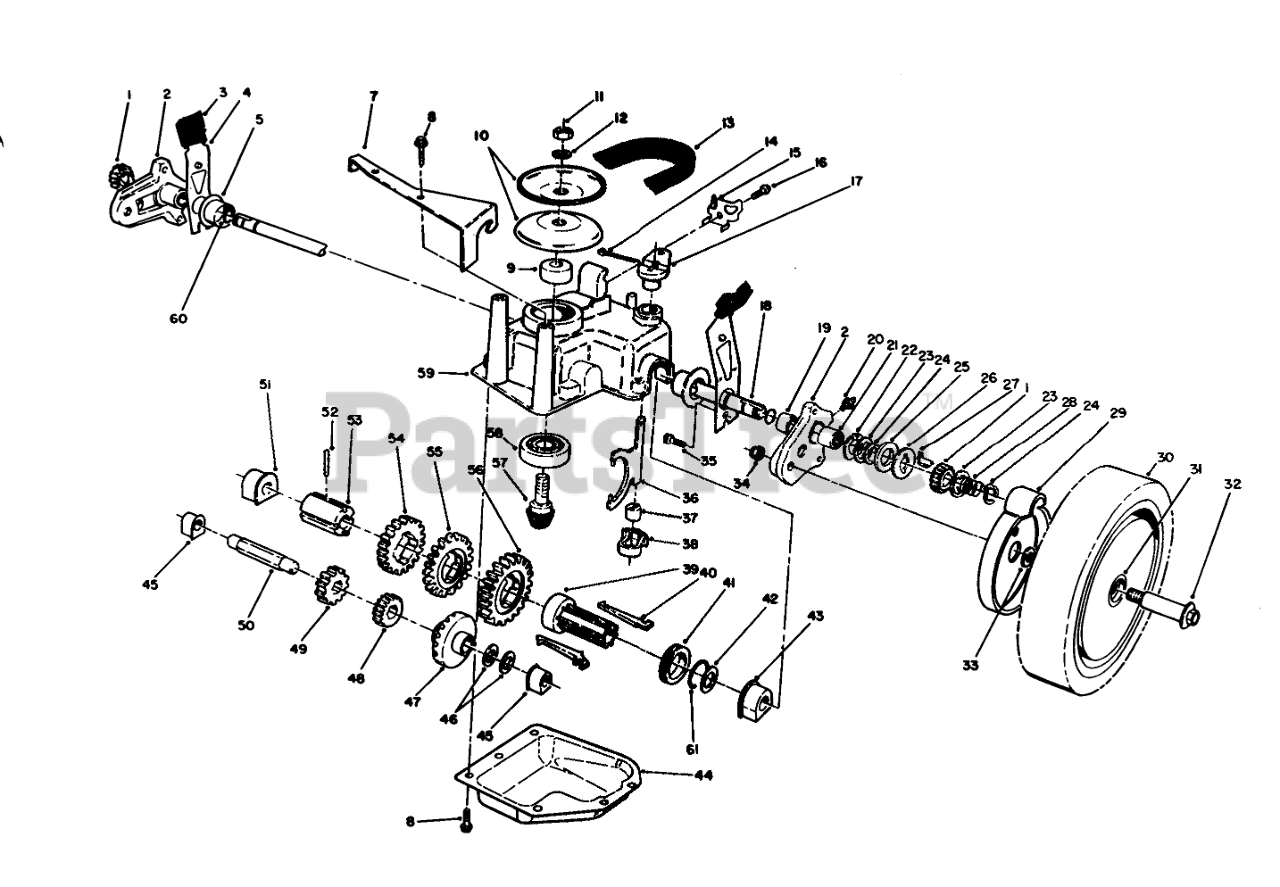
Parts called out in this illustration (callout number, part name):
1	Pinion
2	Pivot Arm Assembly (Incl. Ref #19, 20, &21)
3	KNOB-ARM
4	SPRING ARM ASM SP
5	CAP-END
7	Bracket-Guide
8	SCREW-HWHTF
9	SPACER
10	Pulley Half
11	NUT-HEX
12	WASHER-FLAT
13	V-BELT E
14	PIN-COTTER
15	CLAMP-CABLE
16	SCREW-HWHTF
17	Lever-Shift
18	SHAFT-OUTPUT
19	BUSHING
20	FITTING-GREASE
21	BEARING-ROLLER
22	WASHER-ARM, PIVOT
23	WASHER-THRUST, KEYED
24	RING-CLIP, LOCKING
25	RING-FRICTION
26	WASHER-CLUTCH
27	KEY-ROCKING, LH
28	SPRING-COMPRESSION
29	COVER-WHEEL
30	Wheel-Tire & Gear Ass-y (Incl. Ref . #31)
31	BUSHING
32	WHEEL BOLT
33	SPACER-COVER, WHEEL
34	Nut
35	SCREW-HWH
36	YOKE-SHIFT
37	BUSHING-YOKE
38	RETAINER-FORK, SHIFT
39	SLEEVE-KEY, SHIFT
40	KEY-SHIFT
41	COLLAR-SHIFT
42	Washer
43	BUSHING-OUTPUT
44	Cover-Gearcase
45	BUSHING
46	WASHER-THRUST
47	Gear-Bevel
48	PINION-20T
49	PINION-25T
50	SHAFT-INTERMEDIATE
51	BUSHING
52	PIN-SPRING
53	SLEEVE-GEAR
54	GEAR-39T
55	GEAR-44T
56	GEAR-49T
57	Gear-Pinion
58	BEARING-BALL
59	CASE-GEAR, UPPER
60	O-RING
61	CLIP-SPRING
